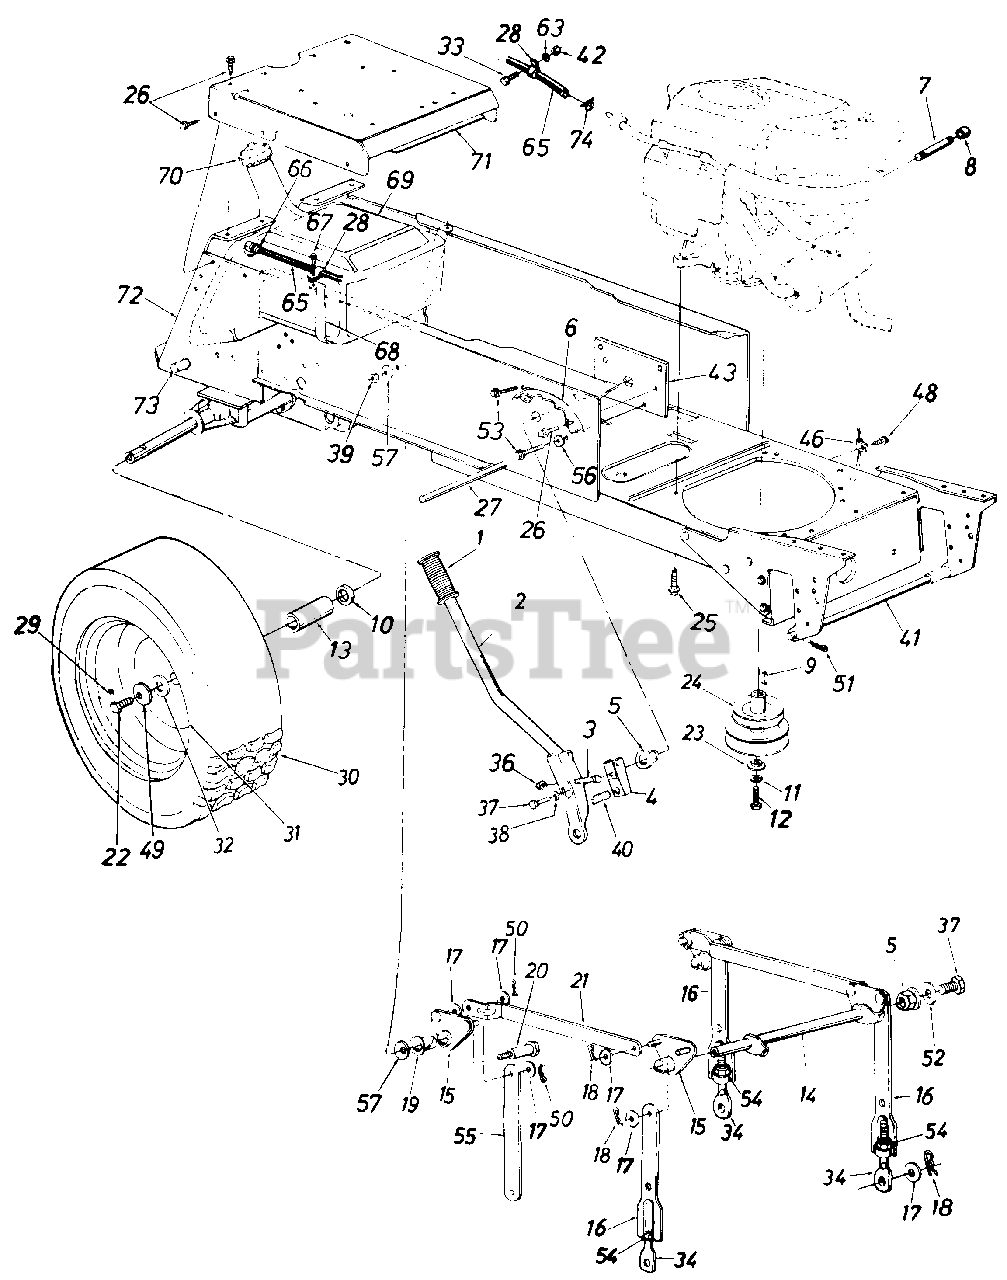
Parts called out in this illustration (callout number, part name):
1	Grip
2	Lift Handle Ass'y.
3	Hex Bolt 5/16-18 x 1.5" Lg.
4	Lift Shaft Drive
5	Plastic Hex Brg. 5/8" I.D.
8	Pipe Cap 3/8-18 Npt.
9	Sq. Key 1/4" x 1/4" x 1.50" Lg.
10	Fl-Wash. .76" I.D. x 1.49" O.D.
11	L-Wash. 7/16" I.D.
12	Hex Scr. 7/16-20 x 1.50" Lg.
13	Sleeve .75" I.D. x 1" O.D.
14	Lift Shaft Ass'y.
15	Lift Pivot Brkt. Ass'y.
17	Fl-Wash. 1/2" I.D. x 1.00" O.D. x .090"
18	Hairpin Cotter
19	Nyliner 5/8" I.D. x .88" Lg.
20	Shld. Bolt 5/8" Dia. x .96" Lg. 3/8-16
23	Flat Wash. .44" I.D. x 1.25" O.D. x .17"
24	Engine Pulley
25	Hex Wash. Hd. Scr. 3/8-16 x 1.25" Lg.
26	Hex Thd, Rolling Scr. 5/16-18 x .75" Lg.
27	Running Board Rod
28	Clamp
29	Air Valve
32	Flat Wash. .34" I.D. x 2" O.D.
33	Hex Bolt 1/4-20 x .62" Lg.
34	Eye Bolt Adj. Link 1/2-13 Thd.
36	Hex Cent. L-Nut 5/16-18 Thd.
37	Hex Bolt 5/16-24 x .62" Lg.
38	L-Wash. 5/16" I.D.
39	Hex Top L-Nut 3/8-16 Thd.
40	Compression Spring
41	Deck Connecting Rod
42	Hex Nut 1/4-20 Thd.
48	Hex Wash. Hd. TT-Tap Scr. 1/4-20 x .5" Lg.
49	Bell-Wash. .39" I.D.
50	Cotter Pin .09 Dia. x 1.0" Lg.
51	Int. Cotter Pin
52	Flat Wash. .34" I.D. x 1.12" O.D. x .125"
53	Hex Wash. Hd. AB-Tap Scr. 5/16-24 x .5" Lg.
54	Hex Nut 1/2-13 Thd.
56	Fl-Wash. .344" I.D.
57	Bell-Wash. .4" I.D. x 1.13" O.D.
63	L-Wash. 1/4" I.D.
65	Fuel Line 46" Lg.
66	Hose Clamp
67	Hex AB-Tap Scr. 1/4 x .62" Lg.
68	Fuel Tank Strap
69	Gas Tank
70	Gas Gauge
74	Hose Clamp
